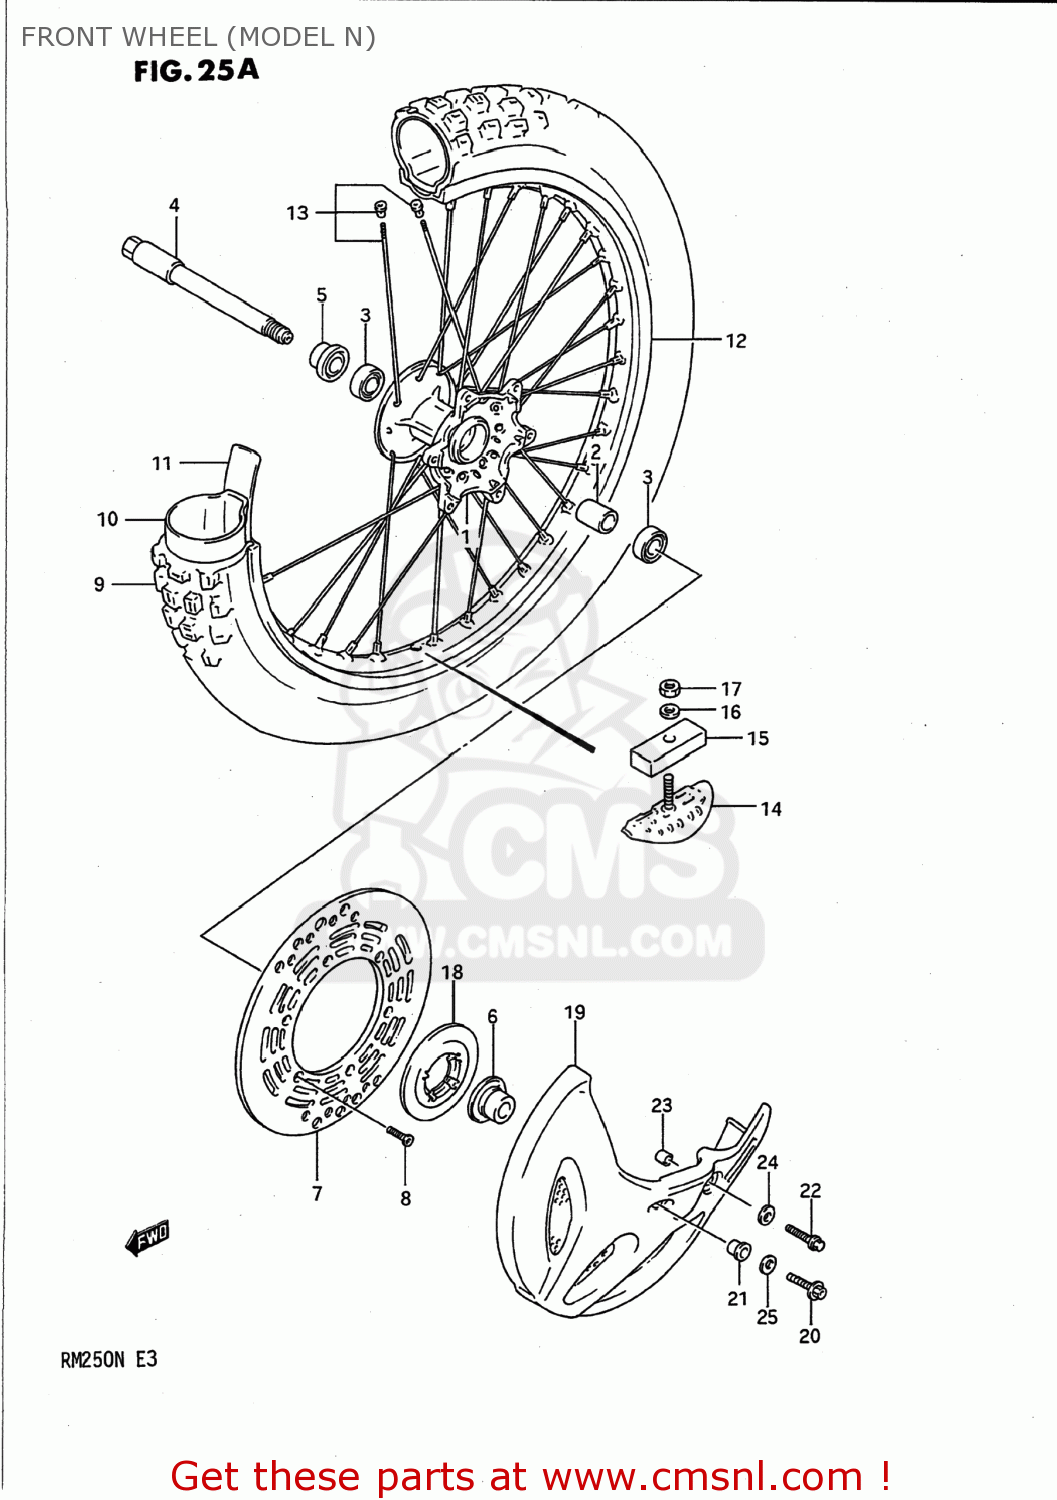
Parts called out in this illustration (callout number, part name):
1	HUB,FRONT
2	SPACER,FRONT HUB BEARING
3	BEARING
4	AXLE,FR
5	SPACER,FR AXLE,R
6	SPACER,FRONT AXLE,LEFT
7	DISC,FR BRAKE
8	SCREW
9	TIRE,FRONT 80/100-21
10	TUBE
11	PROTECTOR,WHEEL,INNER
12	RIM,FRONT WHEEL (1.60X2
13	SPOKE SET,FRONT
14	STOPPER,BEAD
15	CUSHION,BEAD STOPPER
16	WASHER
17	NUT
18	CAP,FR HUB,L
19	COVER,FR BRAKE DISC
20	BOLT
21	WASHER (8.5X16X1.6)
22	BOLT
23	SPACER(6.1X8X14.5)
24	WASHER(6.5X18X1)
25	WASHER(8.5X18X1)
